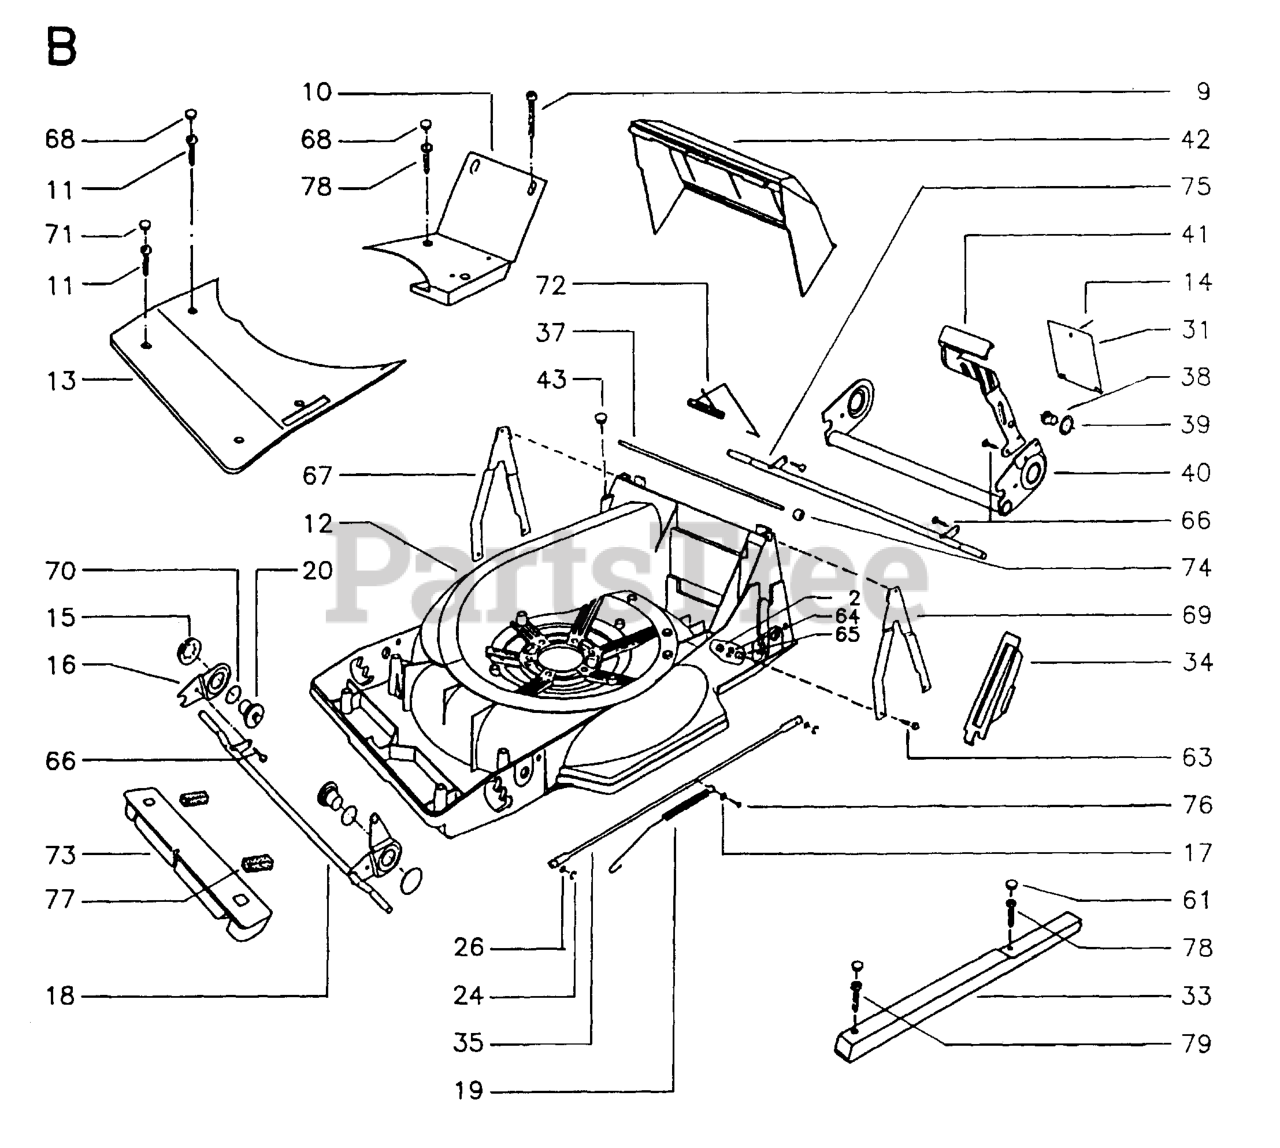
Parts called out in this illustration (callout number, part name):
2	LOCKNUT M8
10	BRACKET 48S
31	REPL BY 516 47 87-00
34	HEIGHT ADJ. COVER
37	REPL BY 516 49 96-01
39	LOCK WASHER
76	SCREW TAPTITE
